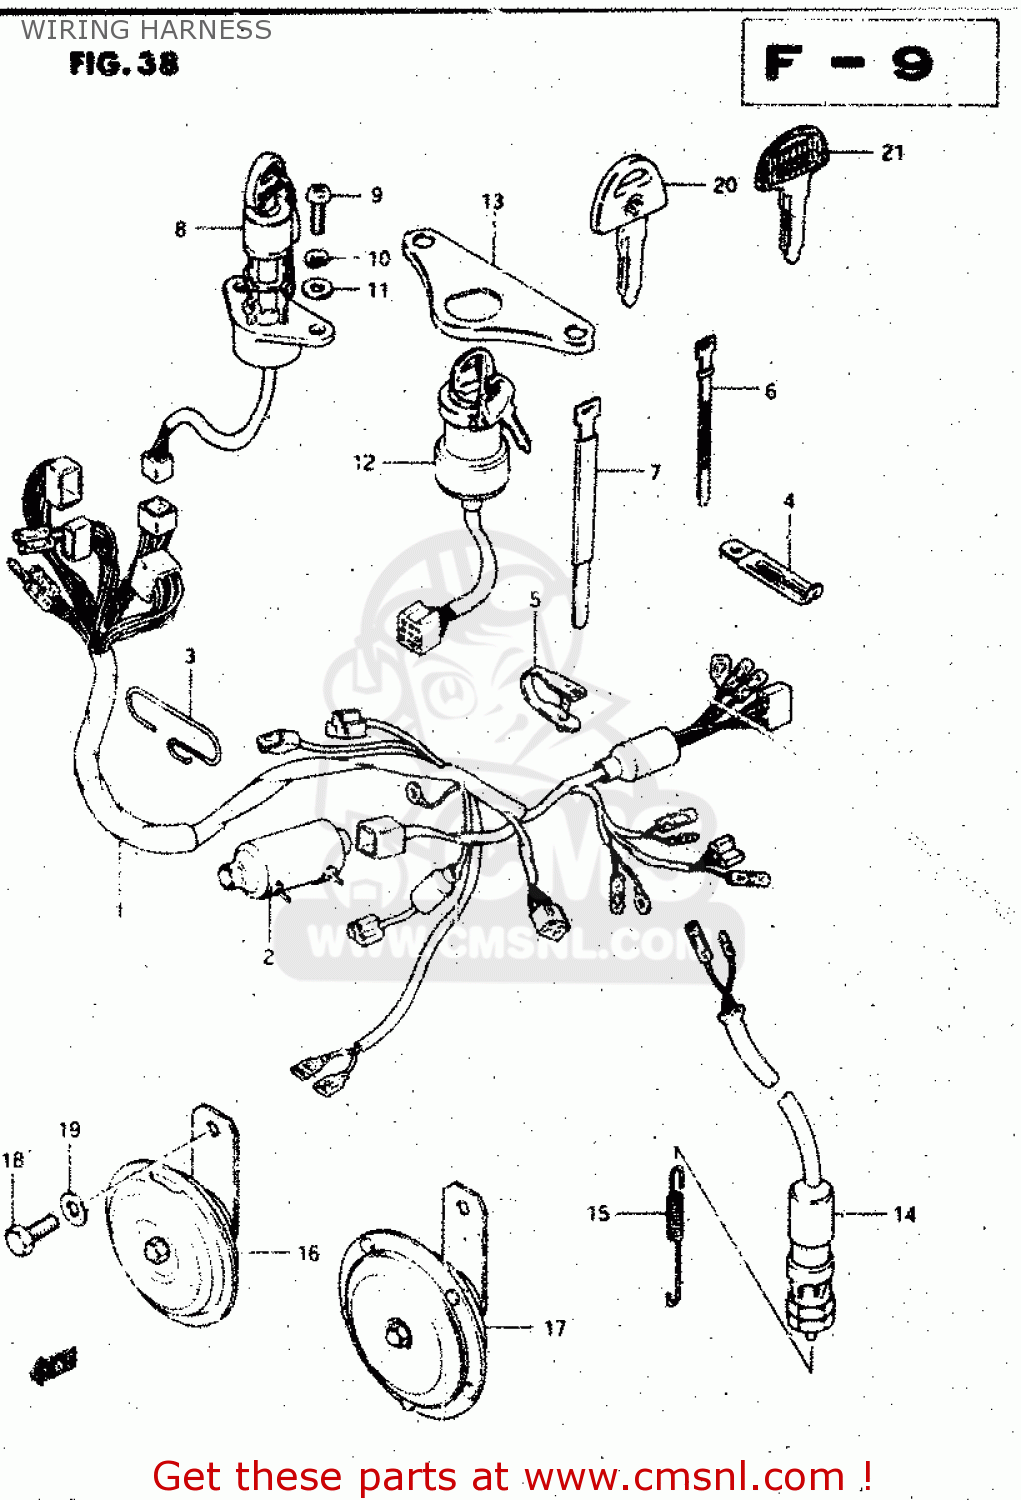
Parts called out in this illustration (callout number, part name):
1	WIRING HARNESS
2	BOOT,WIRING HARNESS
3	CLAMP,WIRING HARNESS
4	CLAMP
5	CLAMP,L:88
6	CLAMP
7	CLAMP
8	SWITCH ASSY,IGNITION
9	SCREW
10	WASHER,LOCK
11	WASHER
12	SWITCH ASSY,IGNITION
13	BRACKET,IGNITION SWITCH
14	SWITCH ASSY,STOP LAMP
15	SPRING
16	HORN ASSEMBLY
17	HORN ASSY
18	BOLT
19	WASHER
20	KEY,BLANK
21	KEY,BLANK
